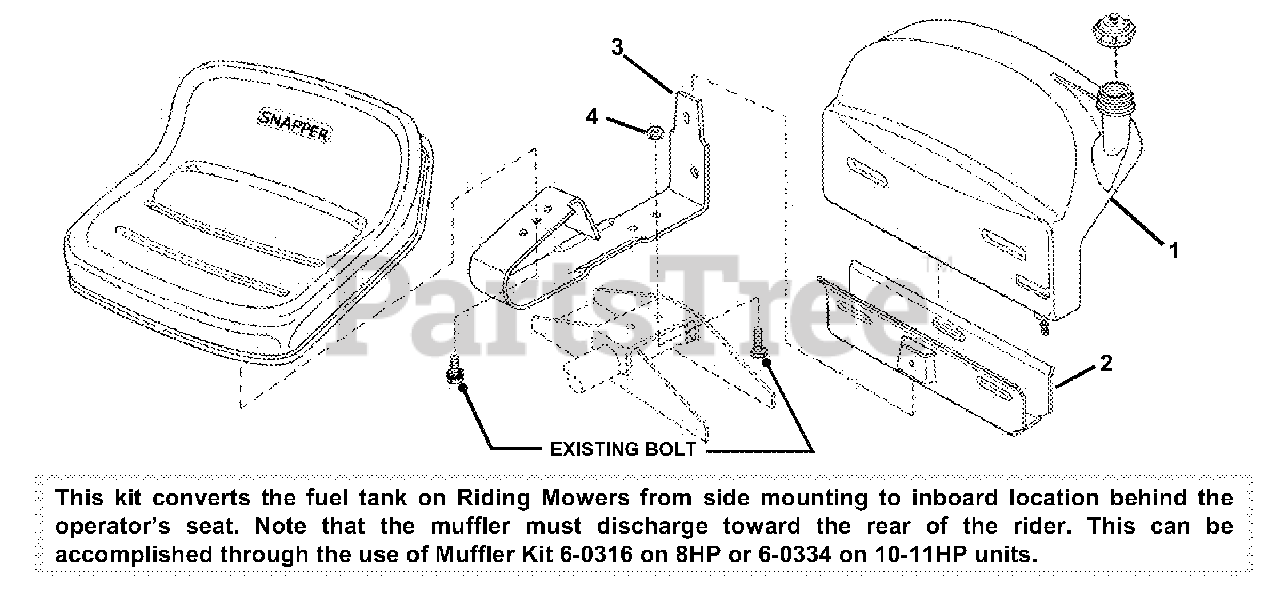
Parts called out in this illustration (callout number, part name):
1	ASSEMBLY, Gas Tank
2	BRACKET, Tank
3	SEAT SPRING
4	NUT, 3/8-16 Hex
